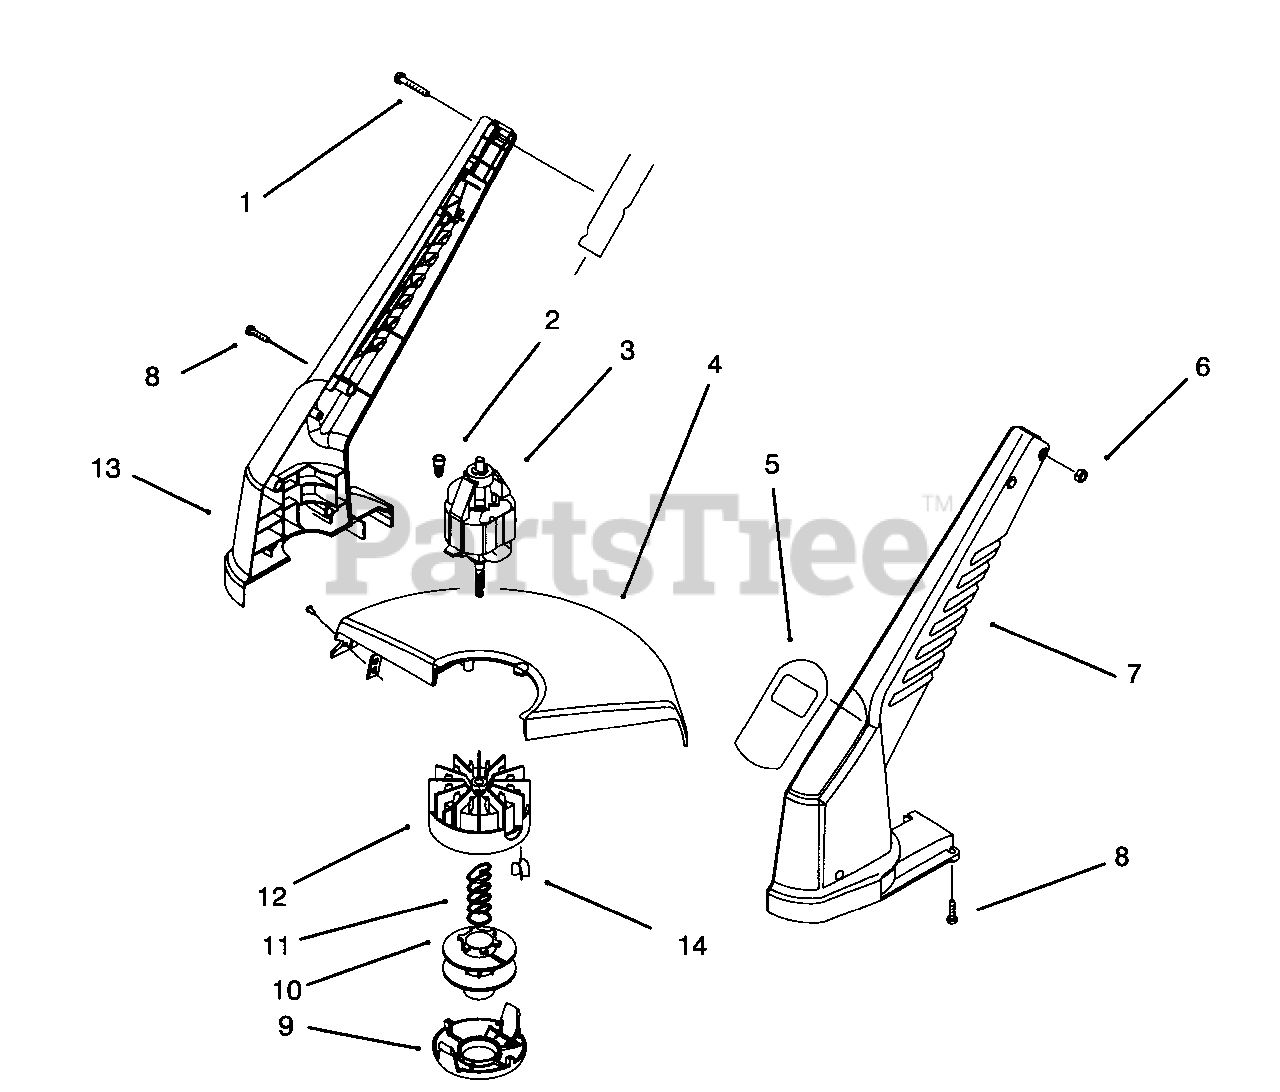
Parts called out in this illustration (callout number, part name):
1	Screw-Pan Hd. Tap
2	Connector-Wire Nut
3	Motor Assembly (Incl. Ref. #12 &-14)
4	Shield-14"
5	Decal-14" Trimmer
7	Housing L.H.
8	Screw-Pan Hd. Tapping
12	Drum
13	Housing R.H.
